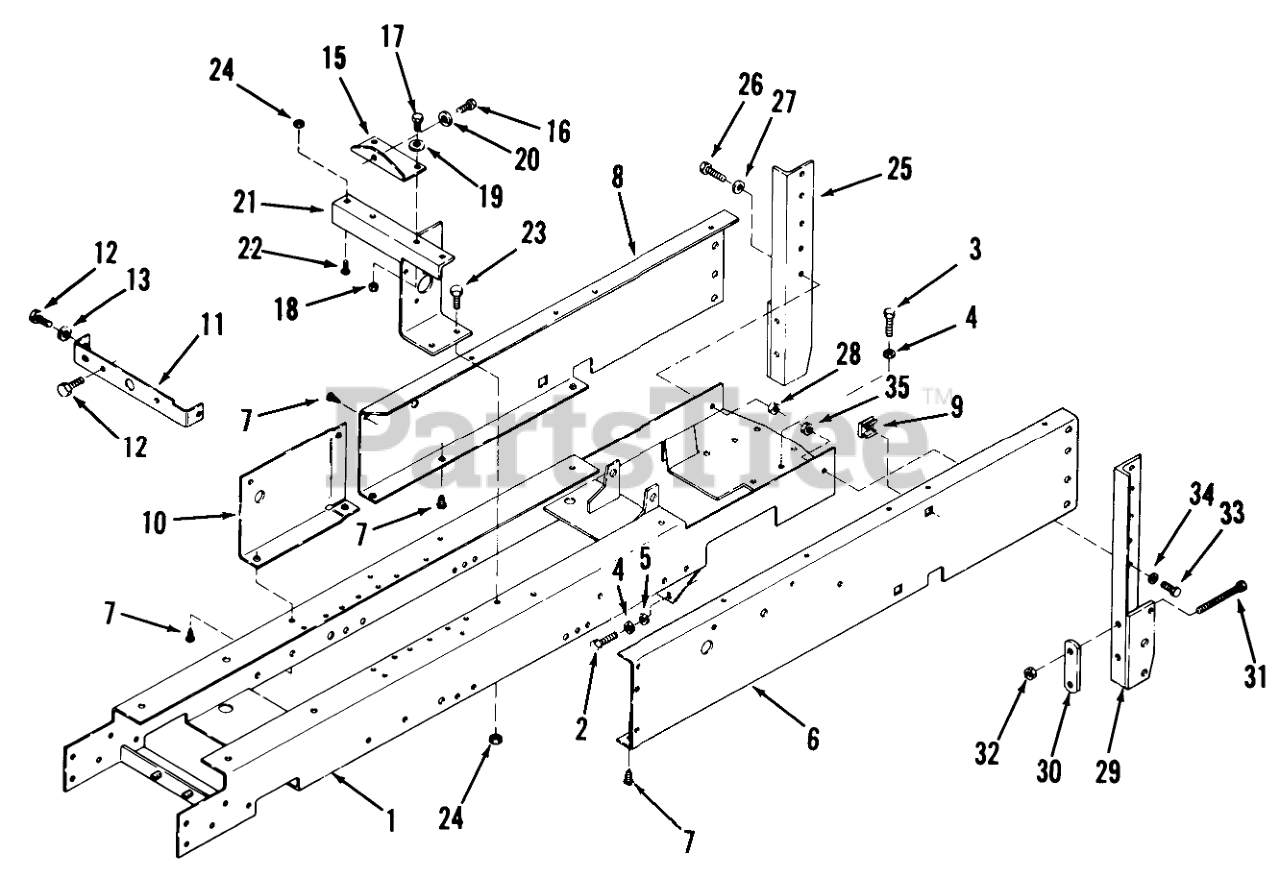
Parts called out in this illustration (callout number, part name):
1	Assy-Frame
2	Bolt
3	BOLT
4	LOCKWASHER
5	Washer
6	Side Panel, L.H.
7	Bolt
8	Hex Nut
9	Nut-Tinnerman
10	Access Plate
11	PLATE-PUMP MOUNTING
12	SCREW
13	WASHER 5/16 SAE
15	Pump Hanger Bracket
16	Bolt
17	HHCS
18	Nut
19	WASHER 5/16 SAE
20	LOCKWASHER
21	Steering Gear Support
22	Bolt
23	BOLT
24	NUT
25	Assy-Angle RH
26	BOLT
27	Washer
28	NUT
29	Assy-Angle LH
30	BRACKET-REAR LINK MOUNTING
31	HHCS
32	NUT
33	BOLT
34	Washer
35	Nut
